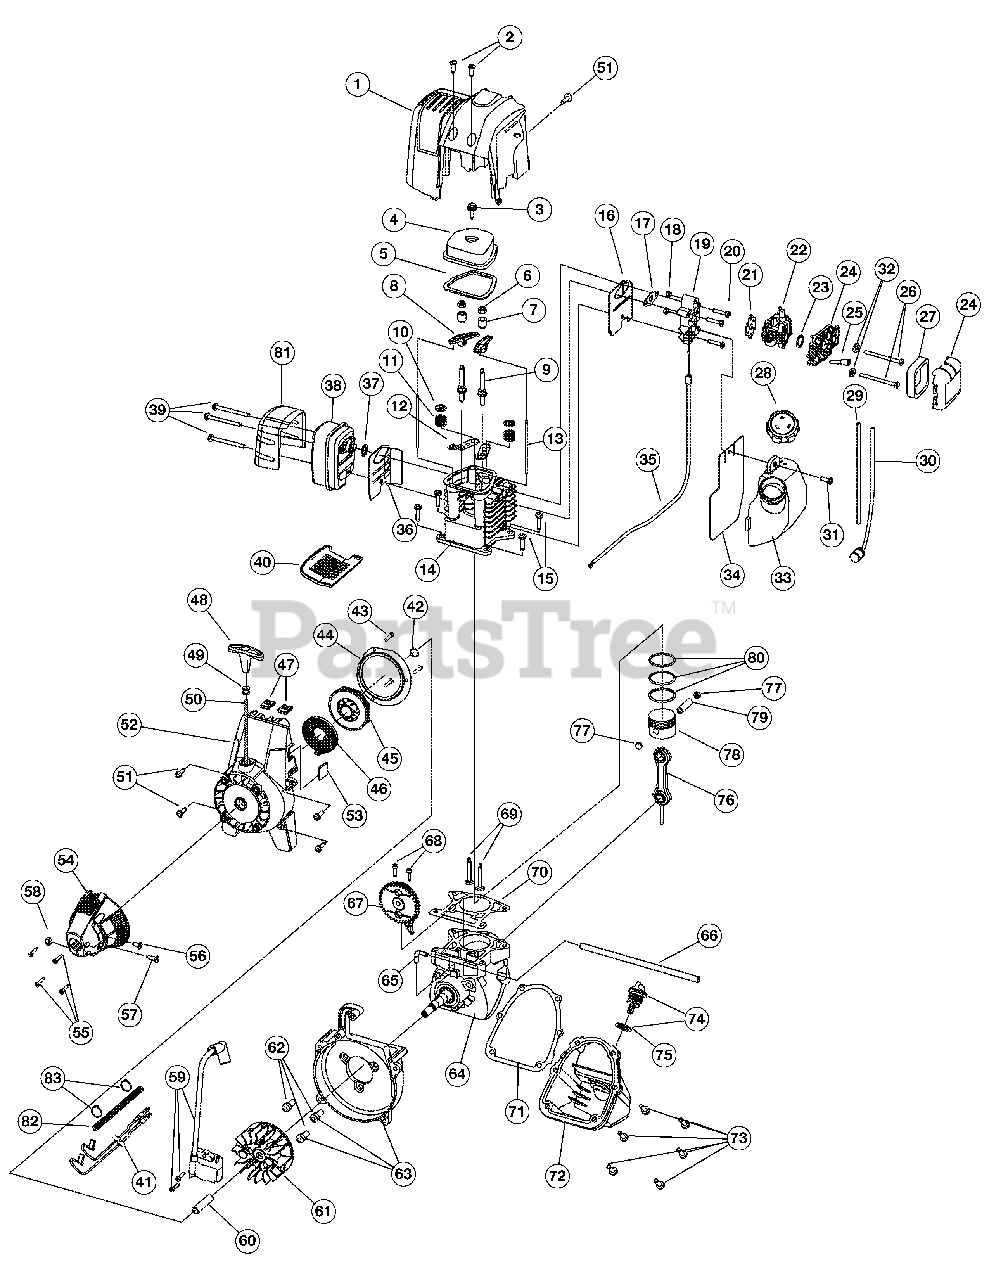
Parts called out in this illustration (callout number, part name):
1	Engine Cover
2	Engine Cover Screws
3	Valve Cover Screw
4	Valve Cover
5	Valve Cover Gasket
6	Rocker Adjustment Nut
7	Rocker Arm Pivot
9	Rocker Arm Stud
10	Valve Spring Retainer
11	Valve Spring
12	Push Rod Guide
14	Cylinder Assembly (includes 9-12, 15, 69 & 70)
15	Cylinder Screw
16	Intake Baffle
17	Carburetor Mount Gasket
18	Nut
19	Carburetor Mount (includes 18)
20	Carburetor Mount Screw
21	Carburetor Gasket
22	Carburetor w/Primer
23	O-Ring, Carburetor
24	Air Filter Cover Assembly (includes 27)
25	Breather Tube
26	Air Filter Mounting Screw
29	Fuel Return Line
30	Fuel Pick-Up Line with Filter
31	Screw
33	Fuel Tank Assembly (includes 28-30)
34	Fuel Tank Shield
35	Throttle Cable
36	Muffler Baffle
37	Muffler Gasket
38	Muffler (includes 37)
39	Muffler Mounting Screw
40	Muffler Cover
41	Switch Wire Assembly
43	Plate Screw
44	Pressure Plate Assembly (includes 43)
45	Recoil Pulley Assembly (includes 42 & 50)
46	Recoil Spring
48	Pull Handle
51	Housing Screw
52	Starter Housing Assembly (includes 42-51)
53	Wire Grommet
54	Cover Assembly (includes 55-58)
55	Cover Screw
56	Anti-Rotation Screw
57	Screw
58	Nut
59	Ignition Module with Screws
60	Square Nut Drive
61	Flywheel
63	Shroud Assembly (includes 62)
64	Crankcase Assembly (includes 65 & 66)
66	Breather Hose
67	Cam Bracket Assembly
68	Cam Bracket Screw
69	Valves, Intake and Exhaust
70	Cylinder Gasket
71	Oil Pan Gasket
72	Oil Pan (includes 71 & 73)
73	Oil Pan Screw
74	Dipstick Assembly (includes 75)
76	Connecting Rod
77	Wrist Pin Button
78	Piston (includes 80)
80	Piston Ring Set
81	Heat Shield
82	Wire Lead Cover
83	Cable Clamp
